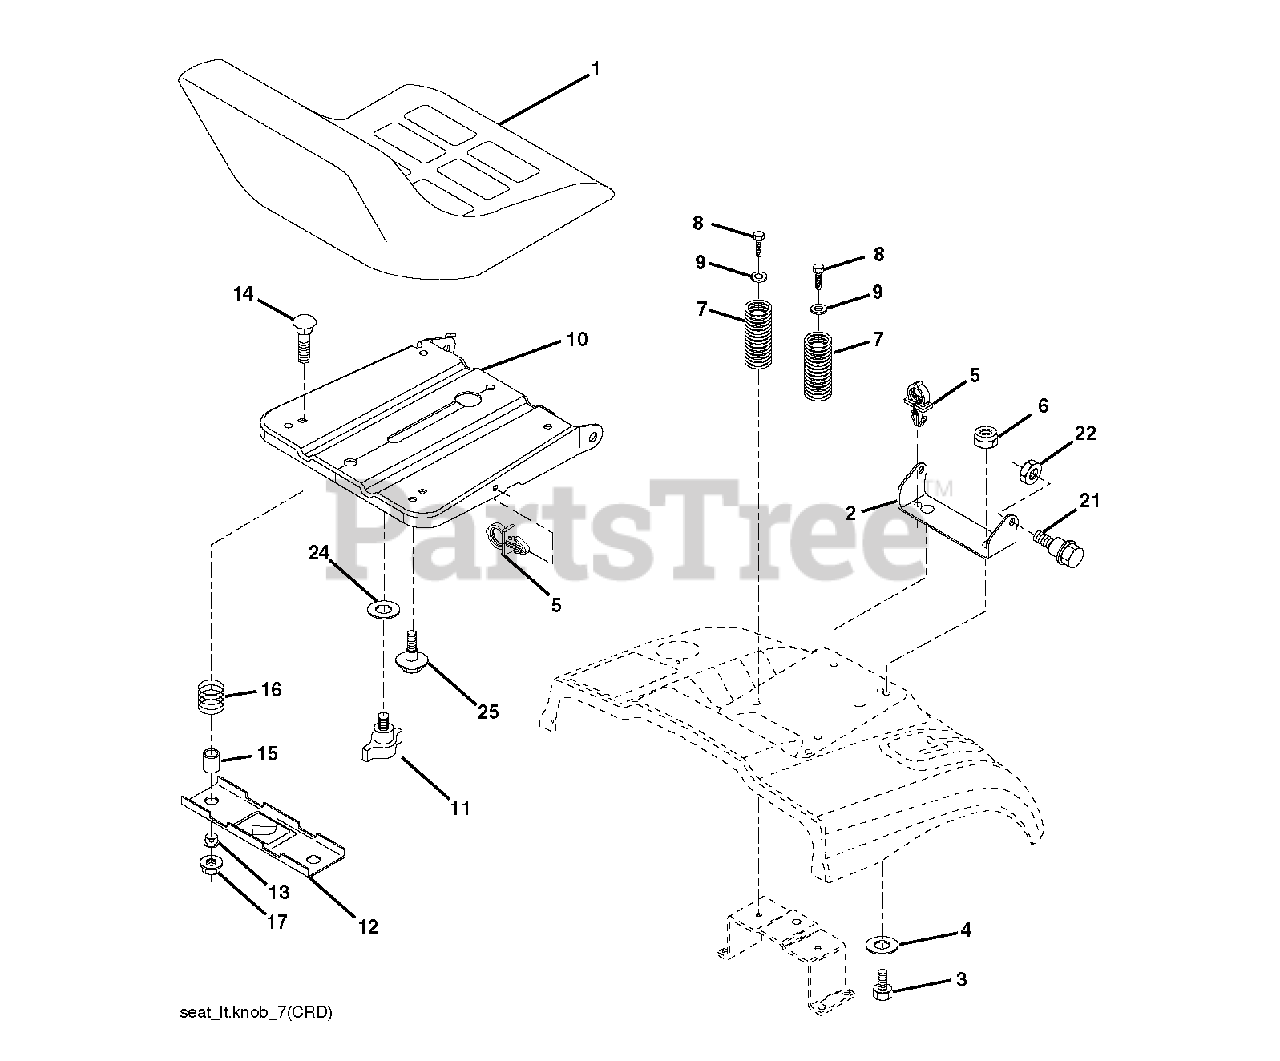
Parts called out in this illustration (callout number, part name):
1	SEAT.XG150.BLK.KB/SLD.NO-LOGO
2	SEAT PIVOT BRKT
4	WASHER PM
5	PUSH CLIP
6	NUT
7	SPRING COMPRESSION
8	SCREW 3/8-16X1
9	WASHER
10	PAN.ASM.SEAT.1SLOT
11	KNOB.SEAT.ADJ.WINGNUT
12	BRKT.MNTNG.SWITCH.SEAT
14	BOLT.ROUND.HEAD.SQUARE.NECK
15	SPACER SPLIT
16	SPRING COMPRESSED
17	NUT T
21	BOLT.SHOULDER.5/16-18
22	NUT.71038.31-18.HEX.NYLOCK
25	BOLT,SHOULD
